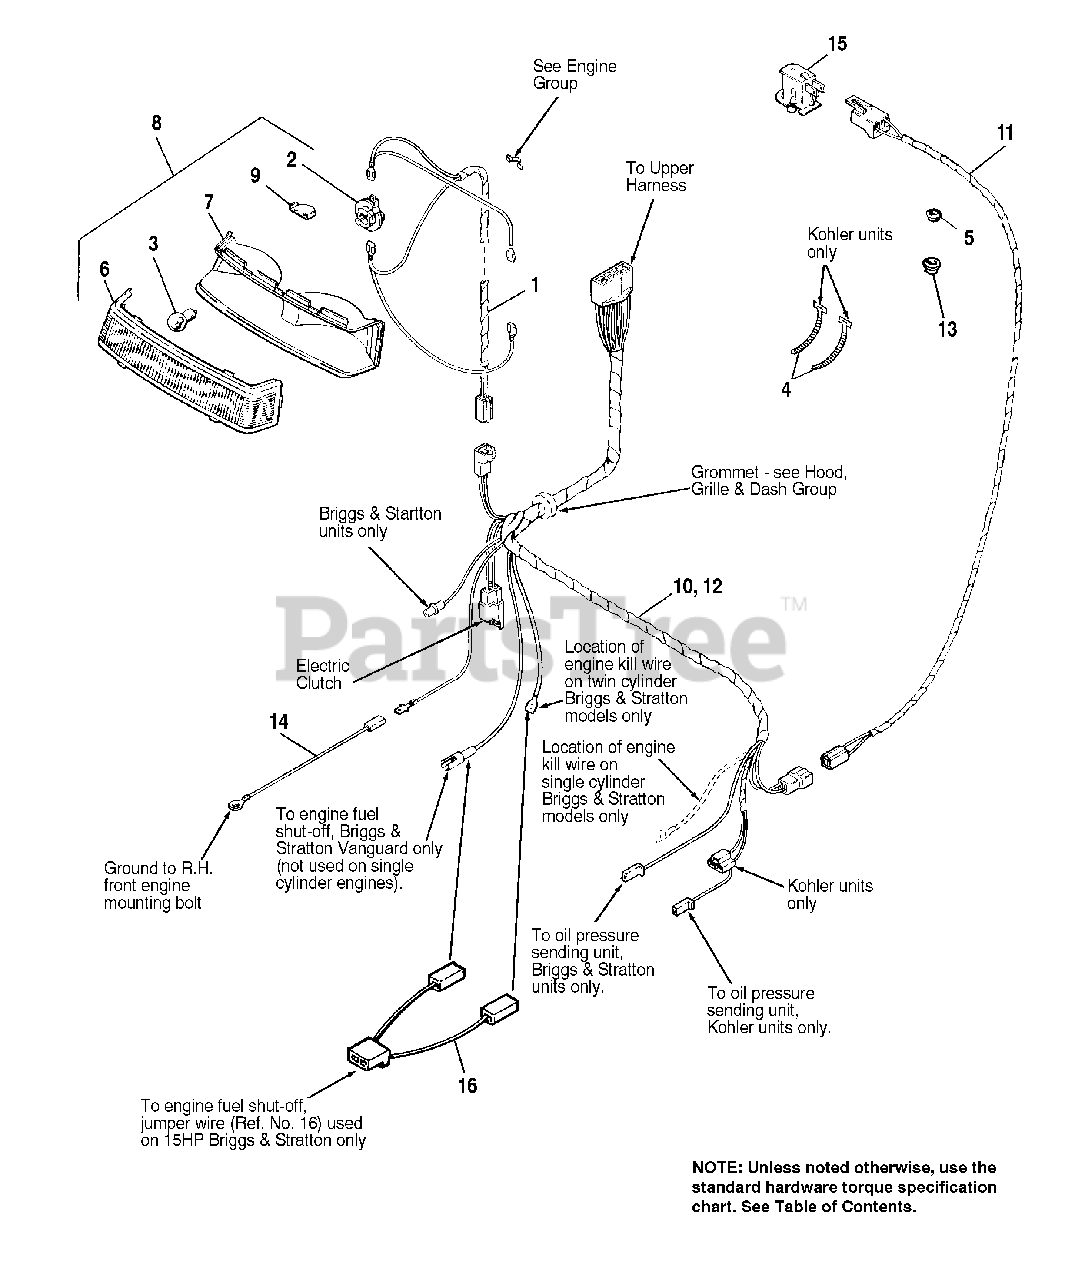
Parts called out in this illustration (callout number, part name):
1	WIRE ASSY., Headlight
2	SOCKET, Bulb
3	BULB, Headlight, 12.8 V
5	BUSHING, Snap, Small
6	LENS, Headlight
7	BEZEL, Headlight
8	HEADLIGHT ASSY.
9	HEAT SHIELD
10	HARNESS ASSY., Lower
11	WIRE ASSY., Seat Switch
12	HARNESS ASSY., Lower
13	BUSHING, Snap, Large
14	WIRE ASSY., Engine Ground
15	SWITCH, Seat, Operator Present
16	WIRE ASSY., Jumper
